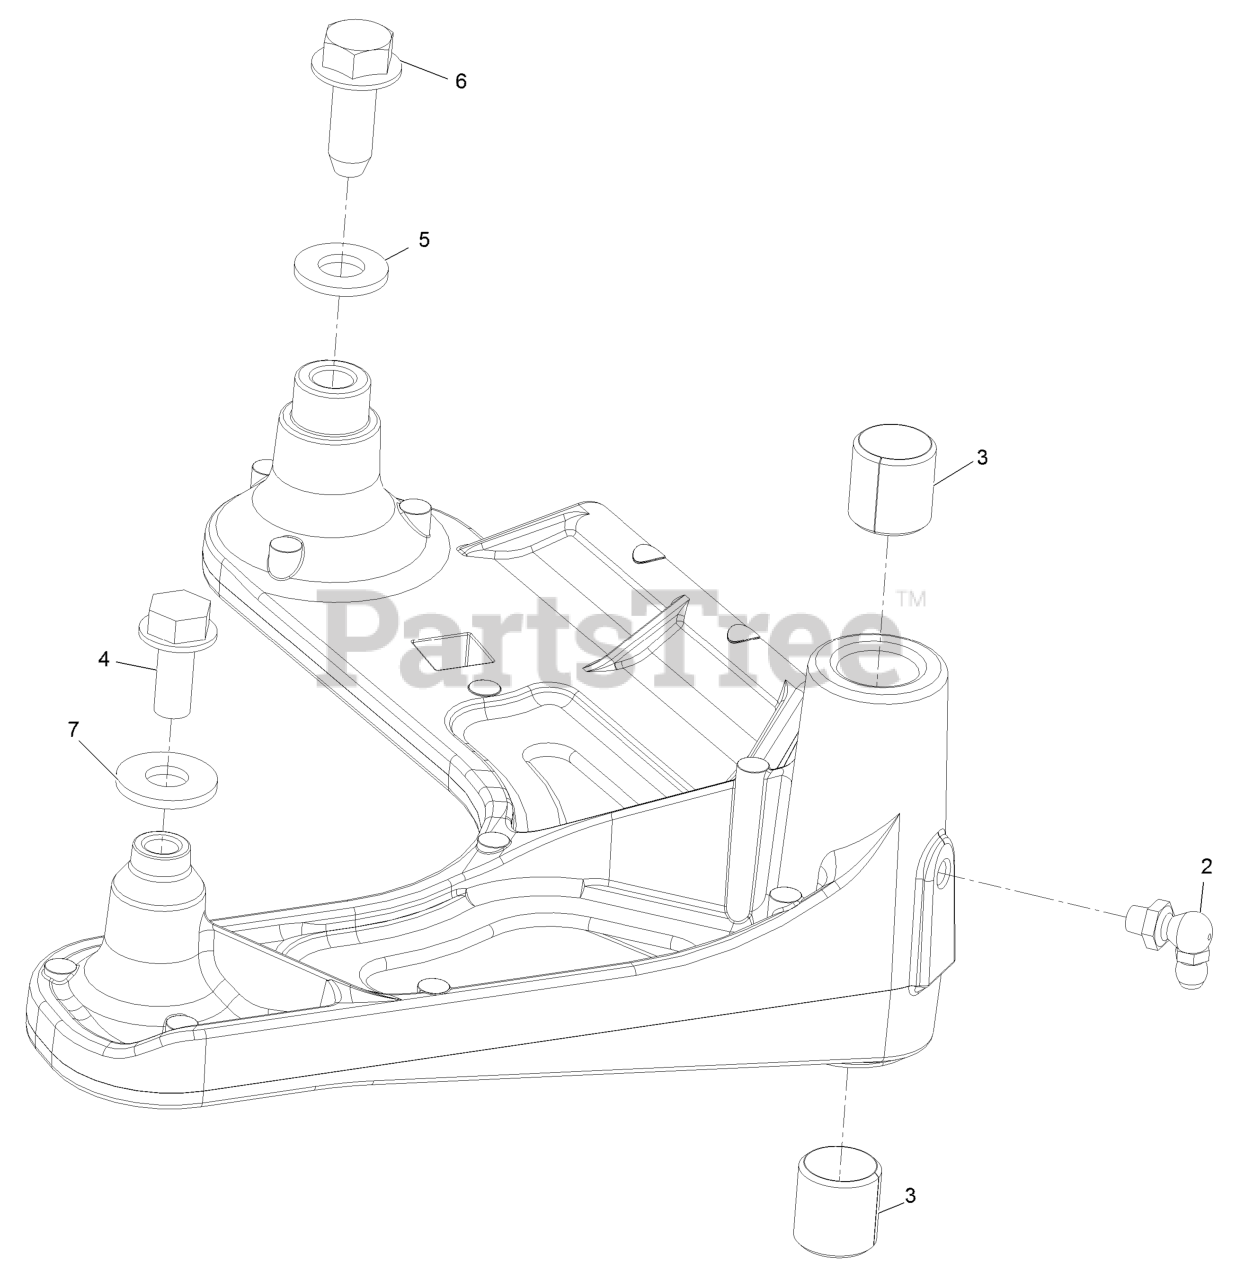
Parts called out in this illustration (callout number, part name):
2	FITTING-GREASE, 90 DEG
3	SLEEVE-BEARING
4	SCREW-THD ROLL, HWH
5	WASHER-FLAT
6	SCREW-FORMING, THREAD
7	WASHER-FLAT
